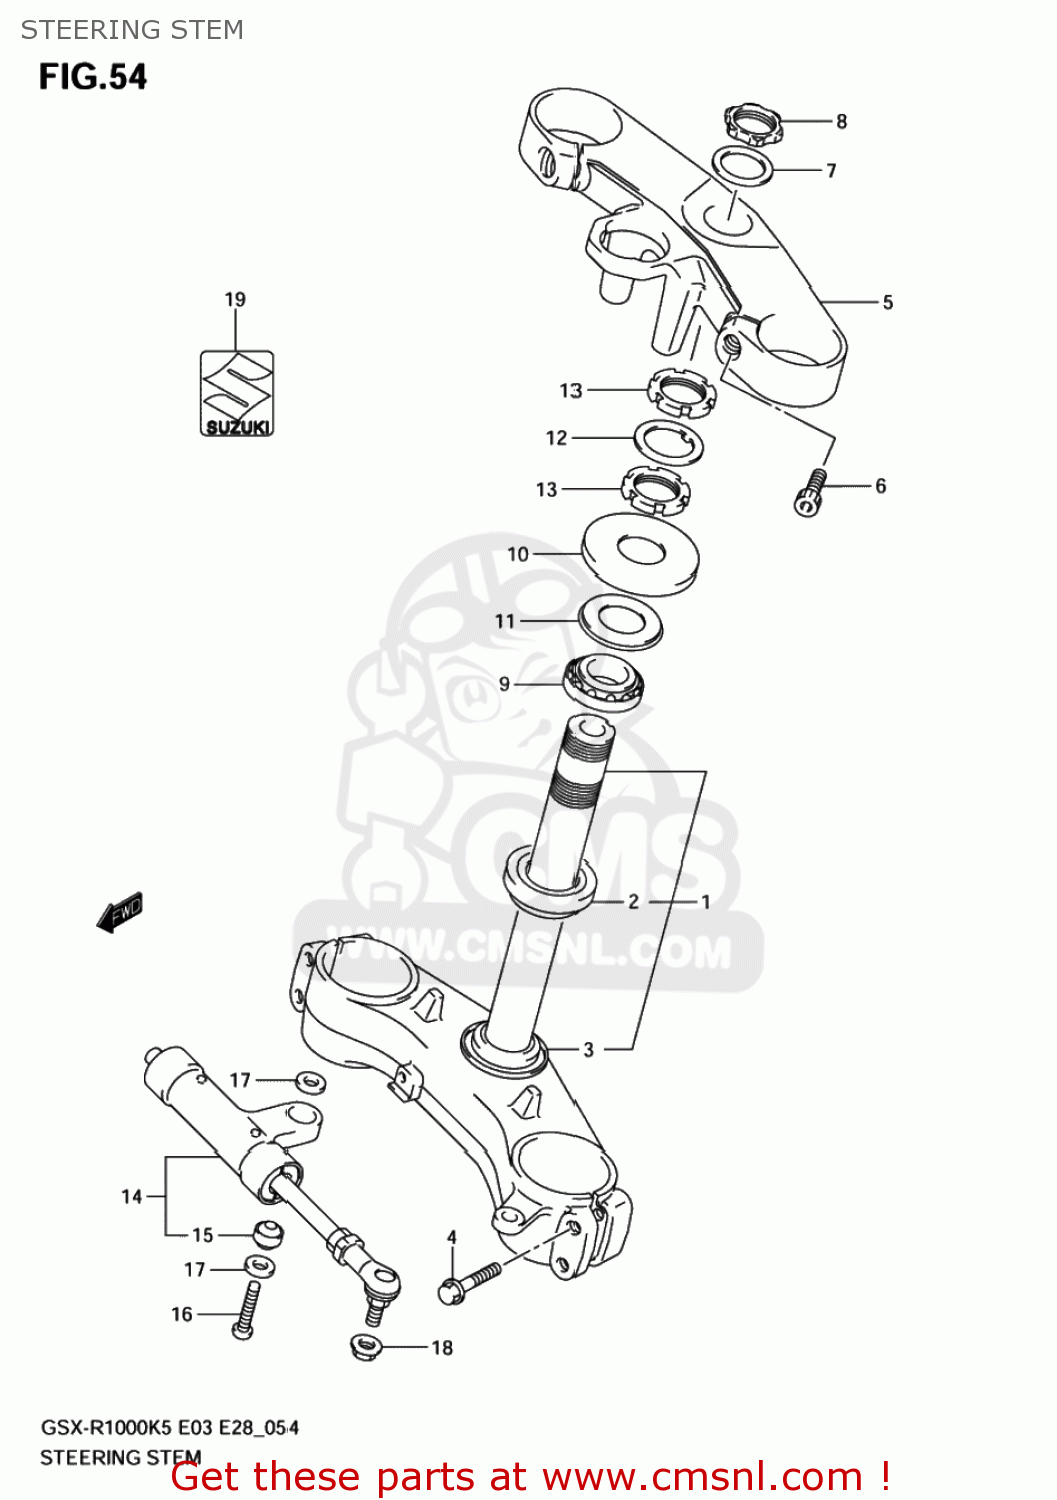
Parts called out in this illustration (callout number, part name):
1	BRACKET,UNDER
2	BEARING(30X55X17)
3	SEAL,STEERING LWR
4	BOLT
5	BRACKET,UPR
6	BOLT
7	WASHER
8	NUT
9	BEARING(30X55X17)
10	COVER,STEERING UPR
11	SEAL,STEERING LWR
12	WASHER,STEERING STEM
13	NUT,STEERING STEM
14	DAMPER ASSY,STEERING
15	BEARING(8X17.5X11)
16	BOLT(8X35)
17	SEAL,PILLOW BALL,DUST
18	NUT
19	EMBLEM,S
